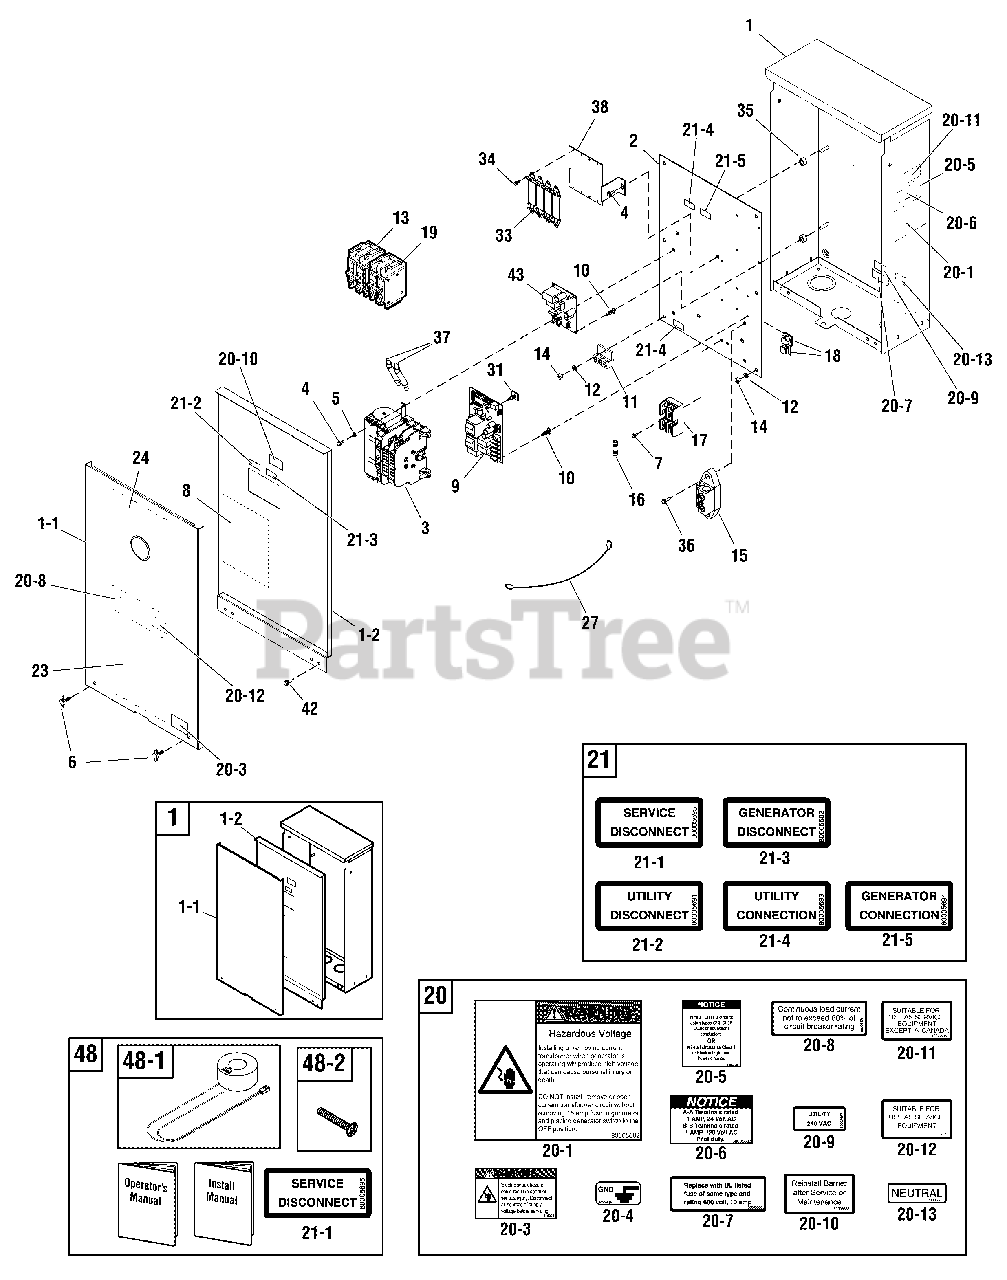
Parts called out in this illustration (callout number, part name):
1	ENCLOSURE
2	BACK PANEL
3	SWITCH, Transfer
4	* TRILOBULAR, #10-32 x 1/2
5	* WASHER, External Tooth, #10
7	* SCREW, Hex Head, Trilobular, #6-32 x 3/8
9	BOARD, Circuit
11	LUG
12	* WASHER, Lock, 1/4
13	BREAKER, Circuit, 100A
14	* NUT, 1/4-20
16	FUSE
19	BREAKER, Circuit, 100A
20	DECAL SHEET - WARNINGS
20-1	DECAL, Warning Voltage
20-3	DECAL, Warning Shock
20-4	DECAL, Ground
20-5	DECAL, Notice
20-6	DECAL, Contacts Rated
20-7	DECAL, Fuse, 10 Amp
20-8	DECAL, Breaker, Circuit
20-9	DECAL, Sensing, Utility
20-10	DECAL, Reinstall After
20-11	DECAL, Not Suitable
20-12	DECAL, Suit. as Service Equip.
20-13	DECAL, Neutral
21	DECAL SHEET-CONNECTIONS
21-1	DECAL, Service Disconnect
21-2	DECAL, Disconnect Utility
21-3	DECAL, Gen Disconnect
21-4	DECAL, Connection, Utility
21-5	DECAL, Connect Gen
27	WIRE
34	* TRILOBLAR, 8-32 x 3/8
35	SPACER
36	* TRILOBULAR, #10-32 x 3/4
42	* TRILOBULAR, #10-32 x 3/8
48	KIT, Manual ACC
48-1	CURRENT TRANSFORMER
